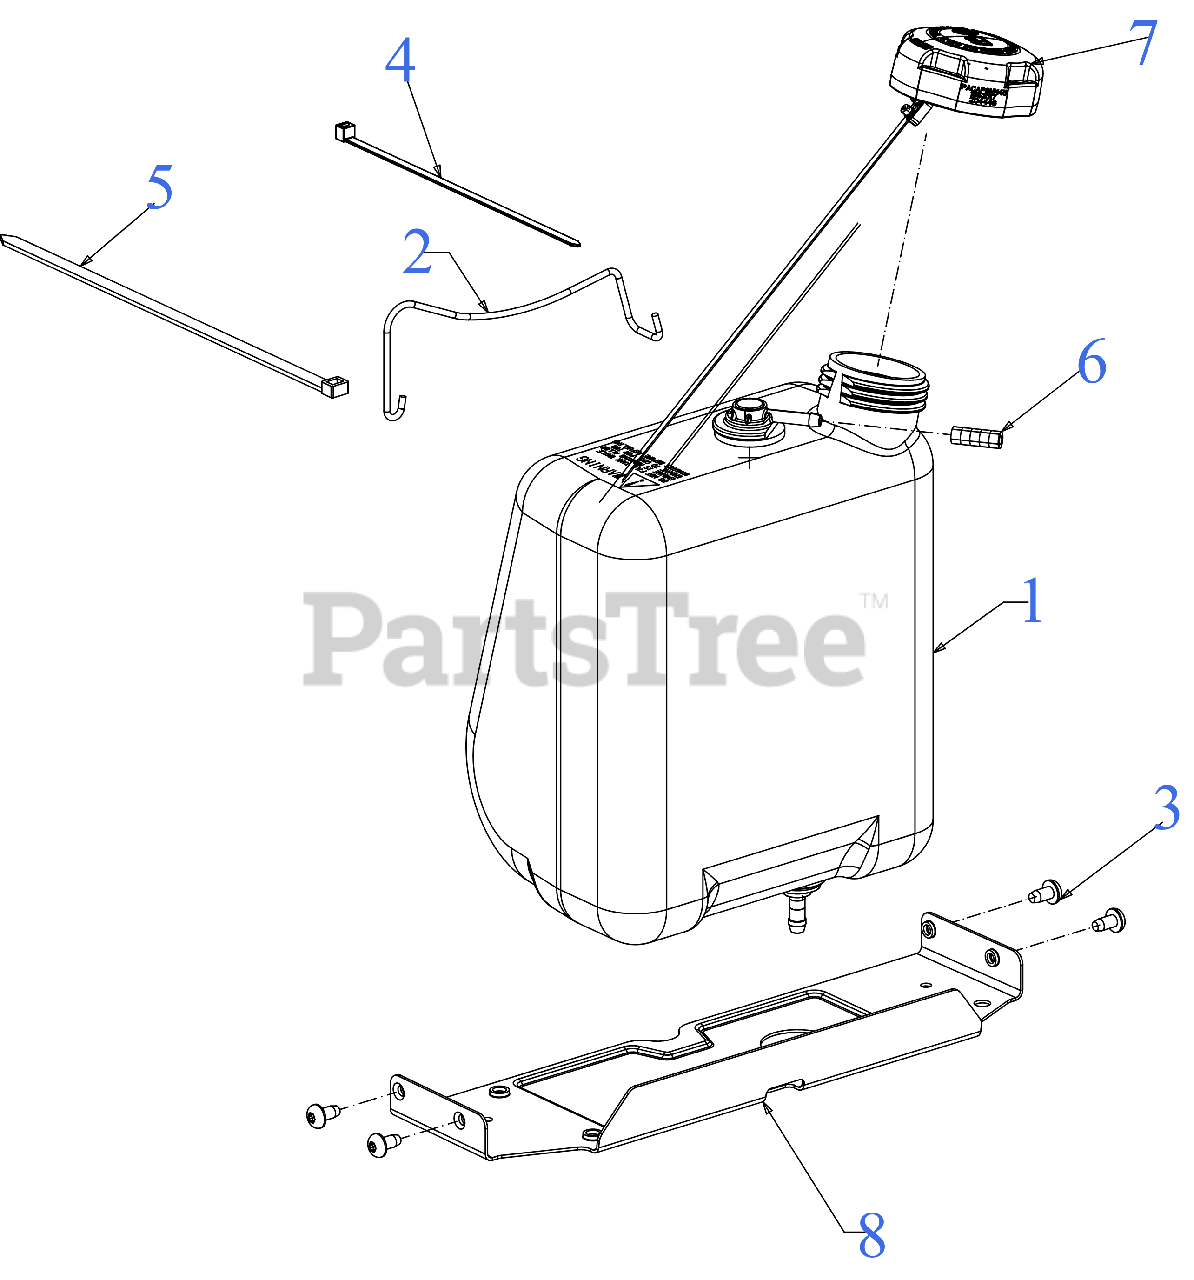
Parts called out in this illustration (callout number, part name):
1	FUEL TANK ASSEMBLY
2	BATTERY ROD ASSEMBLY (POWDER BLACK)
3	SCREW 1/4-20 x .5
4	7" CABLE TIE
5	CABLE TIE 36"
6	VENT HOSE 3/16 ID 45"LG
7	FUEL CAP W/TETHER
8	FUEL TANK BRACKET POWDER BLACK()
